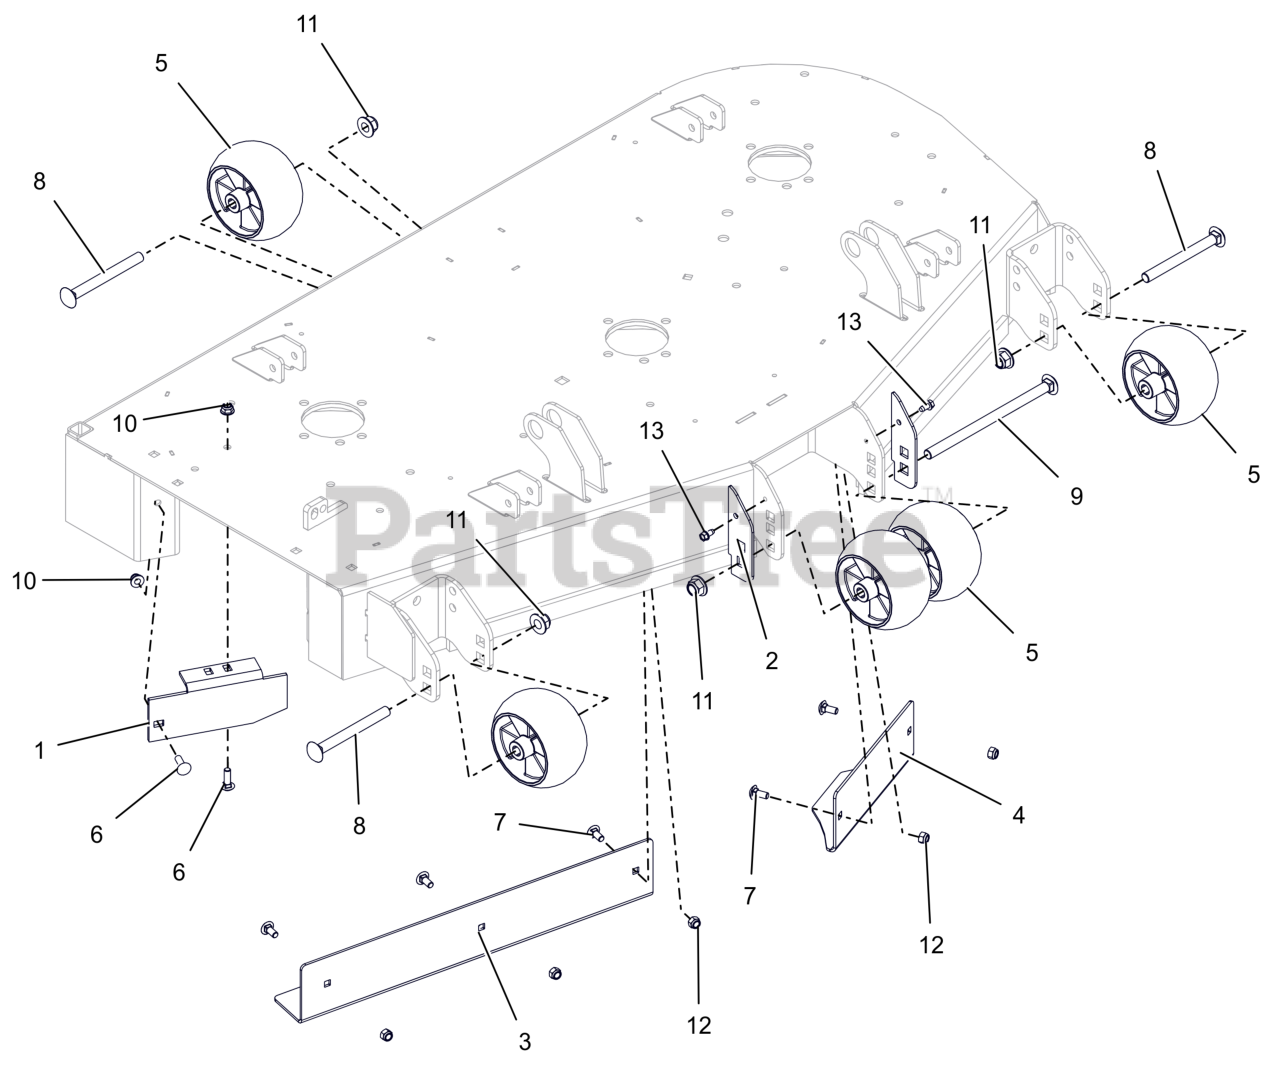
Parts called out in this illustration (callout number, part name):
1	BAFFLE, 44/48" SIDE DISCHARGE
2	PLATE, ANTI SCALP WHEEL EXT.CE
3	BAFFLE, 48" RH VACUUM (ORANGE)
4	BAFFLE, 44/48" LH VACUUM (ORANGE)
5	WHEEL, ANTI SCALP - 5X3 CTR W/RIBS
6	BLT,RHSN .31-18X1.00 G5 ZCC
7	BLT,RHSN .31-18X.75 G5 ZCC
8	BLT, RHSN .50-13X5.00 G5 ZCC
9	BTL,RHSN .500-13 X 8.5S G5 ZCC
10	NUT,LK-NYL-FLG .31-18 G5ZC120
11	NUT,NYL-FLG .50-13 GF ZCC
12	NUT,NYL .31-18 G5 ZCC
13	SCR-TAP .25-20X.50 HWH ZCC
